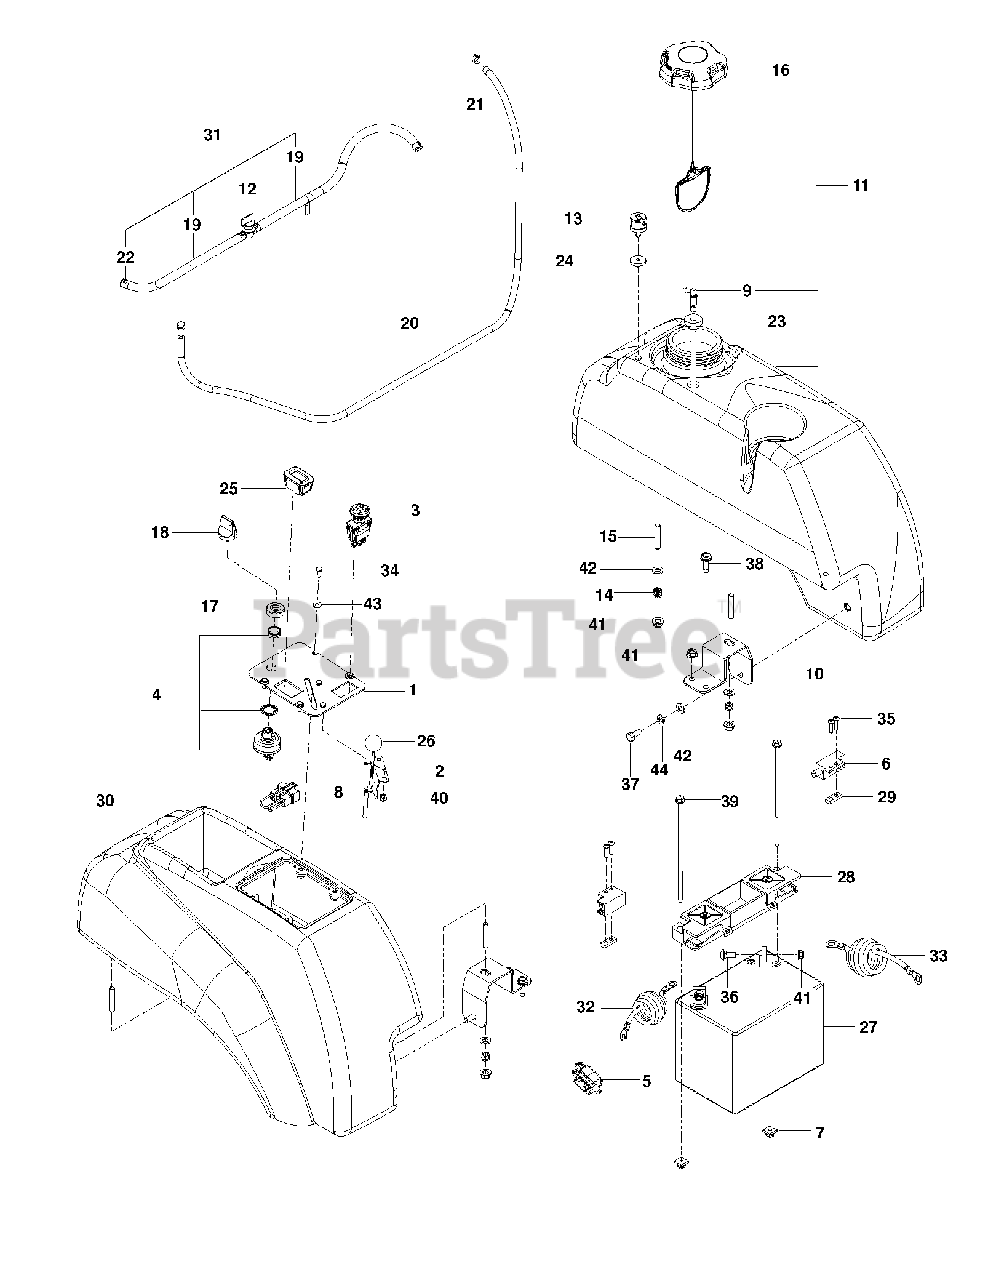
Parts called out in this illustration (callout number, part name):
2	CABLE THROTTLE 39"
3	SWITCH, PTO 10 AMP
4	SWITCH, IGNITION, INDAK
5	SWITCH, BRAKE 3P
6	SWITCH INTERLOCKT
7	PUSH NUT-NYLON
8	PLUG, TIMER
9	FITTING, FUEL
10	SUPPORT, TANK, BLK
11	TANK FUEL LT ASM MZ GRAY
12	FUEL VALVE
13	VALVE.FUEL.CHECK
15	STUD, 5/16C
16	CAP, FUEL
17	CAP IGNITION NUT
18	KEY, IGNITION
19	GAS LINE 10"
20	HOSE, VAPOR 3/16 X 48"
21	CLAMP, HOSE
23	RUBBER GROMMET
24	GROMMET, CHECK VALVE
25	RP GUAGE.SRVCMNDR.HRMTR.
26	KNOB.ROUND.BALL.BLACK
27	BATTERY, 12 V 330 AMP
28	BATTERY HOLD DOWN
29	TAPPED PLATE
30	FENDER CONSOLE
31	FUEL LINE ASM
32	POST.CABLE LONG
33	NEG. CABLE, 28"
34	HCS #10-24 X 1/2
35	SCR #10-24 X .75 SKT HD BLK
36	BOLT 5/16C X 3/4" CARRIAGE
37	HCS 5/16C X 3/4
38	RP BLT 5/16-18 X 1 THRD FORM D
39	Bolt, 1/4-20 X 7.5
40	NUT 10-24 NYLOC
41	5/16-18 NYLOC FLANGE NUT
42	FLAT WASHER 5/16 SAE
43	WASHER #10
44	WASHER 5/16 LOCK
